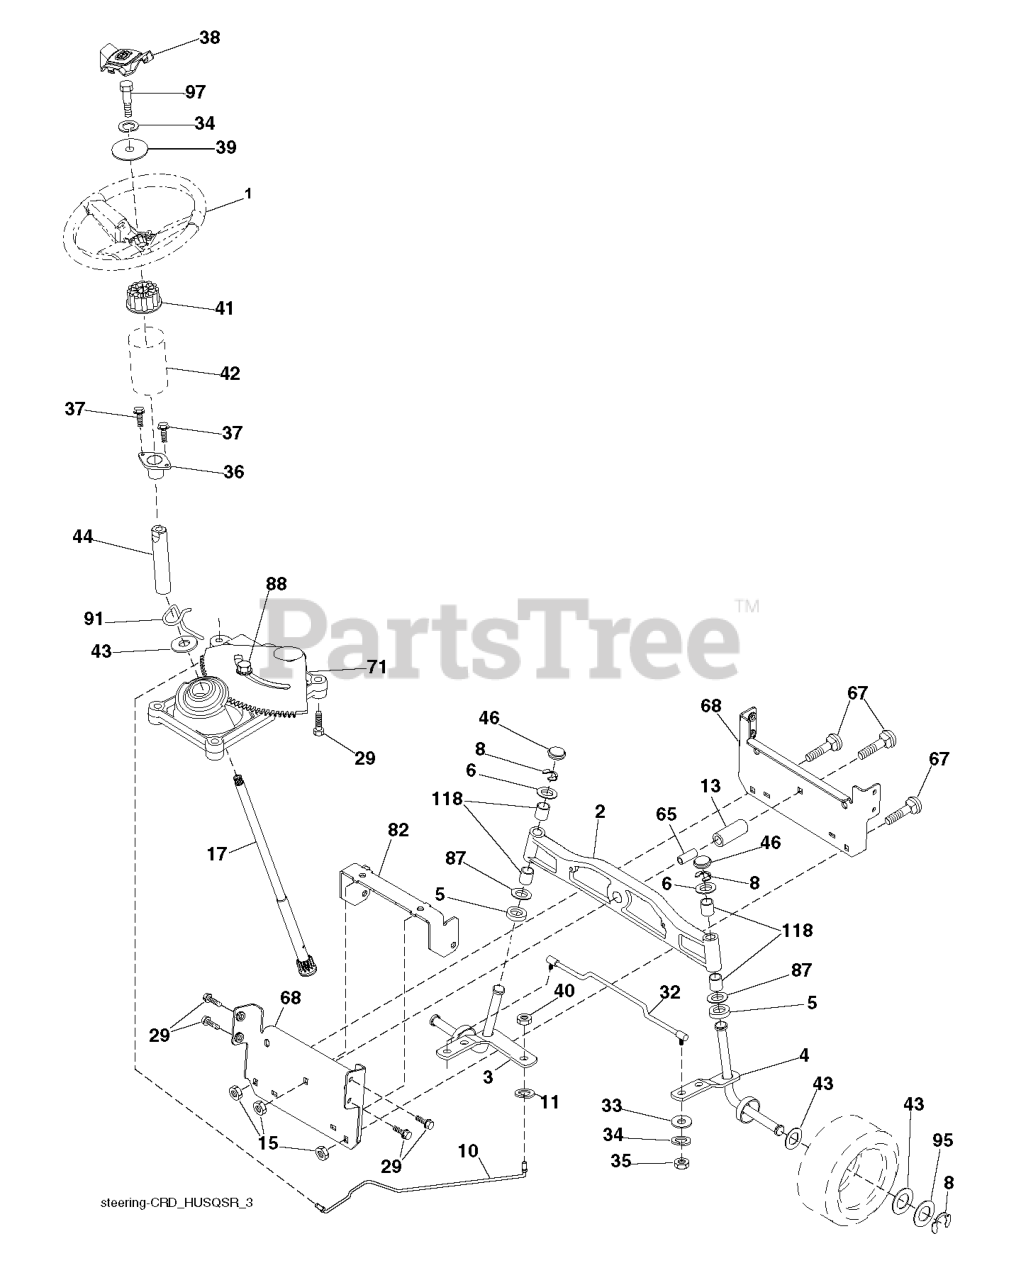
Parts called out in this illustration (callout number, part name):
1	RP WHEEL.STEER.HUSQ.PREM.OVMLD
2	AXLE.ASM.LT.CAST.LGHTWGHT
3	SPINDLE.ASM.LH.15"TIRES
4	SPINDLE.ASM.RH.15"TIRES
5	THRUST WASHER
10	DRAGLINK.15".TIRES.2001
11	WASHER, LOCK 3/8
13	TUBE, PIVOT AXLE
15	NUT
17	SHAFT STEERING SPLINE
29	SCREW, 3/8-16X3/4
33	WASHER M
34	WASHER.LOCK.HVY.HLCL.SPR.5/16
35	NUT, CROWNLOCK
36	BUSHING, STEERING
37	SCREW.TT.#10-32X.5.3/8.FLANGE
38	RP INSERT.CAP.WHL.STRG.HUSQ.
39	WASHER.11/32
40	NUT CROWNLOCK 3/8-24
41	ADAPTER, WHEEL STNG..
42	BOOT, STEERING
44	SHAFT.EXTEN.STRG.SPLINE
46	CAP.SPINDLE.BLACK
65	SPACER.BRACE.AXLE
67	BOLT CARRIAGE
68	BRACE.AXLE.15"TIRES
71	STEERING ASM
82	BRACKET.SUSP.CHASSIS.FRONT.15
87	WASHER, FLAT .781 X 1 1/2"
88	BOLT, SHOULDER 7/16-20
91	CLIP.STEERING
95	WASHER.HARDENED
97	BOLT 5/16-18 X 4 W/PATCH
118	BUSHING, AXLE CAST
